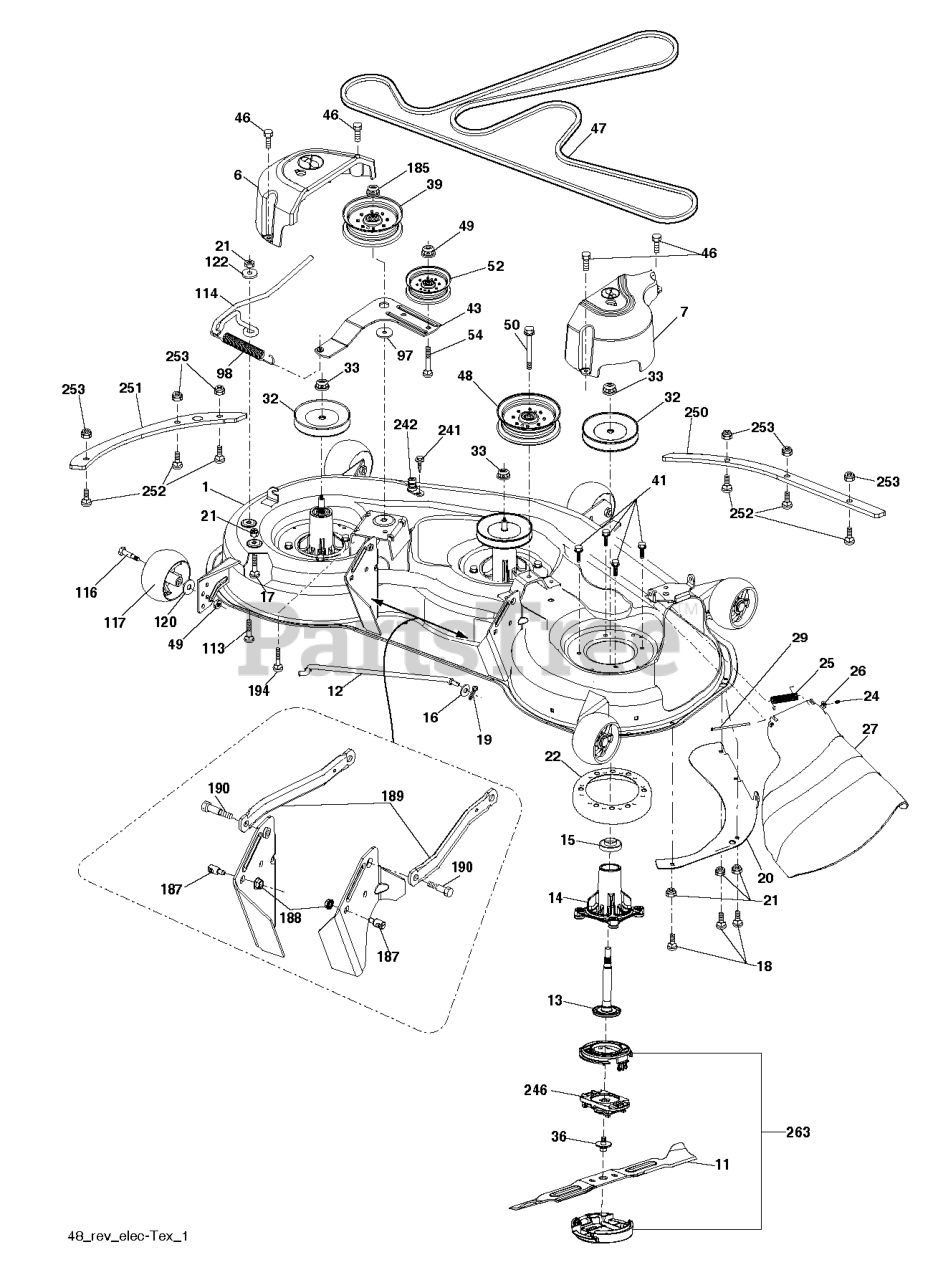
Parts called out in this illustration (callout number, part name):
1	DECK.SVC.48"
2	COVER.MANDREL.LH.46"
6	COVER.MANDREL.LH.48"(2 2)
7	COVER.RH.MANDREL
11	BAGGER.BLADE.48"IN.PNT.431
12	ROD.ANTI.SWAY.48/54"K4
13	RP.SAFT ASM.REV.TALL.N/GREASE
14	RP.HOUSG.MAND.REV.TALL.N/GRS
15	BEARING.MANDREL.TOP.EXTENDED
16	WASHER
17	BOLT.CARR.5/16-18X5/8.SHORT
18	BOLT
19	PIN.COTTER.5/16.BOW TI
20	BAFFLE, VORTEX MWR
21	LOCKNUT
22	STRIPPER.MANDREL.ROUND.BLACK
24	CAP-SLEEVE LT
25	SPRING, TORSION
26	NUT PUSH M
27	DEFLECTOR SUBS TO 532 180655
29	ROD.HINGE
32	PULLEY MANDREL
33	NUT.FLANGE.LOCK.TOP
36	SCREW.SEMS.7/16-20X1.HEX.HEAD
39	RB PULLEY.IDLER.4.50/HUB SPEC
41	BOLT.HEX.WASHR.HED.313-18X1.19
43	ARM.IDLER
46	SCREW.1/4-20X5/8
47	BELT.DRIVE.DECK
48	PULLEY.IDLER.2006
49	NUT LOCK FLG 3/8-16 UNC
50	SCREW TT 3/8-16X2-1/4 UNC
52	AUGER WELDMENT RH
54	BOLT.3/8-16X1.50
98	SPRING, DECK DRIVE
113	BOLT CRT
114	ROD.TENSION.RELIEF.TEX (2 2)
116	BOLT.SHOULDER.3/8-16X3-5/8.
117	RP WHEEL. GUAGE RALLY
120	WASHER
122	BUSHING.RELIEF.TENSION
185	NUT.LOCK.FLANGE.7/16
187	STUD.FASTNER.W/ANTI-ROTATE
188	NUT LOCK HEX FLANGE 5/16-18
189	ARM.SUSPENSION.MOWER
190	BOLT.SHOULDER
194	BOLT.HEX.WASHER.HEAD.7/16-24X
241	SCREW.TT.#10-32X.5.3/8.FLANGE
242	PORT.WASHOUT
246	HOLDER.BLADE.REVOLUTION
250	PLATE.REIN.FRNT.BOLTON.48X431
251	PLATE.REIN.SIDE.BOLT.ON.48X431
252	RHSNB, 1/4-20 X 1, GR5
253	NUT T
263	CAP.REVOLUTION ASM
